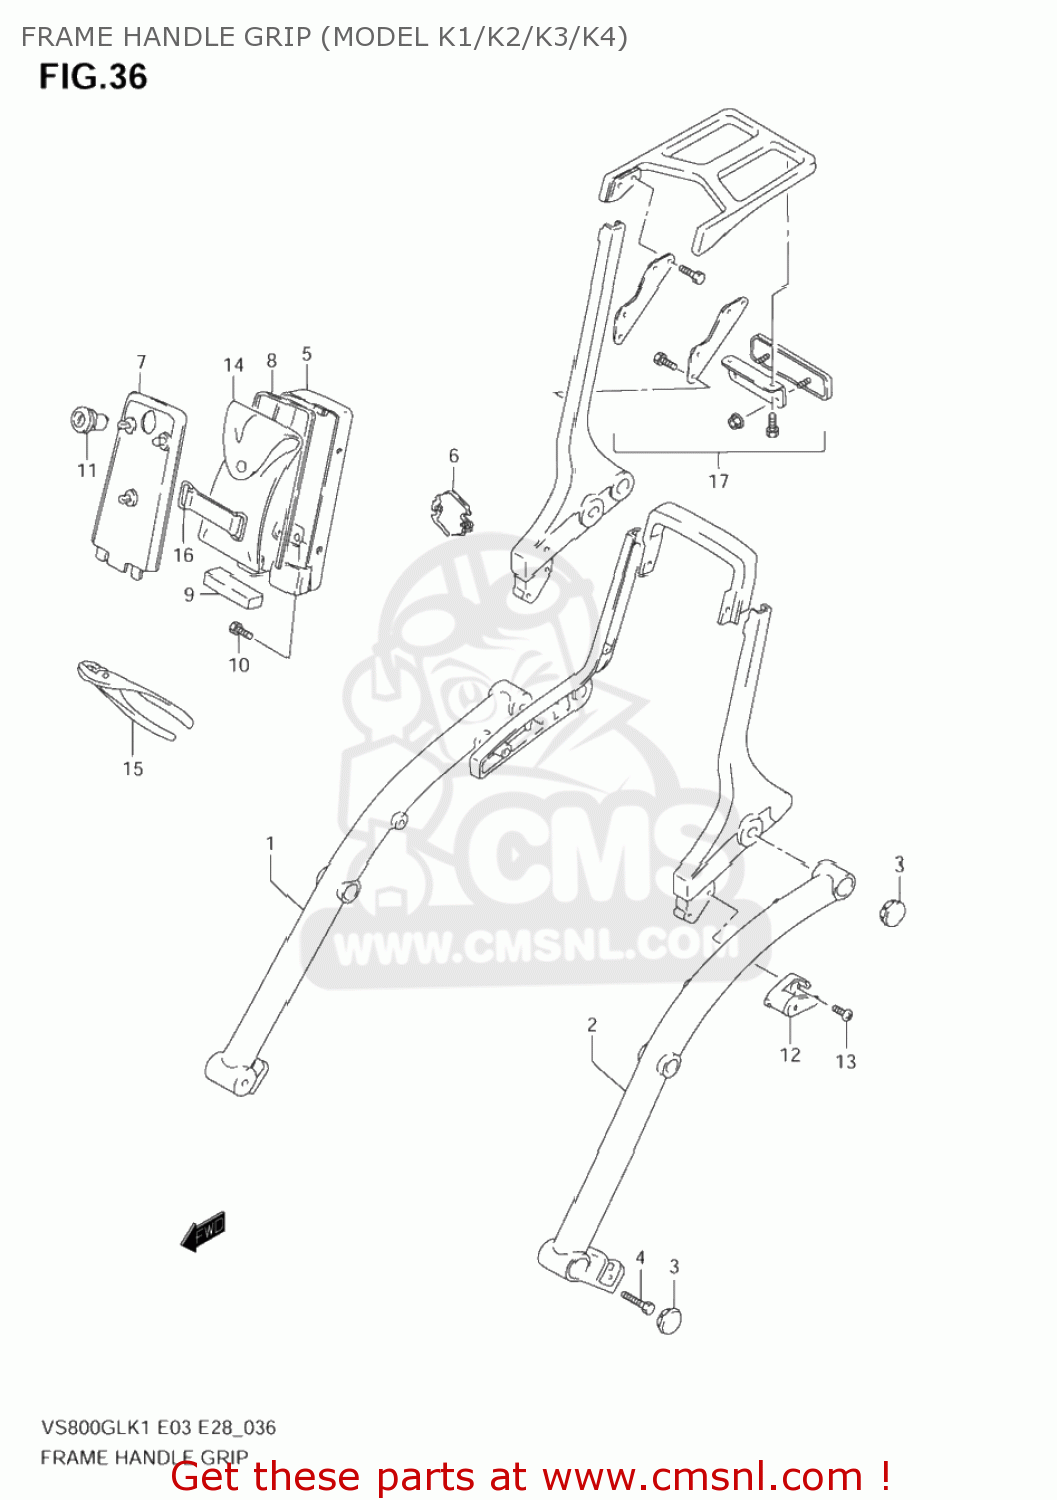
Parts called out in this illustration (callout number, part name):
1	GRIP,FRAME HANDLE,RIGHT
2	GRIP,FRAME HANDLE,LEFT
3	CAP,FRAME HANDLE GRIP
4	BOLT
5	HOLDER,TOOL RR
6	EMBLEM,TOOL HOLDER RR
7	HOLDER,TOOL FR
8	MOLDING,TOOL HOLDER RR
9	CUSHION,TOOL BACK
10	BOLT
11	LOCK SET,TOOL HOLDER
12	LOCK SET,HELMET
13	SCREW
14	TOOL ASSY
15	PLIER(150)
16	BAND
17	CARRIER SET,SPORT
